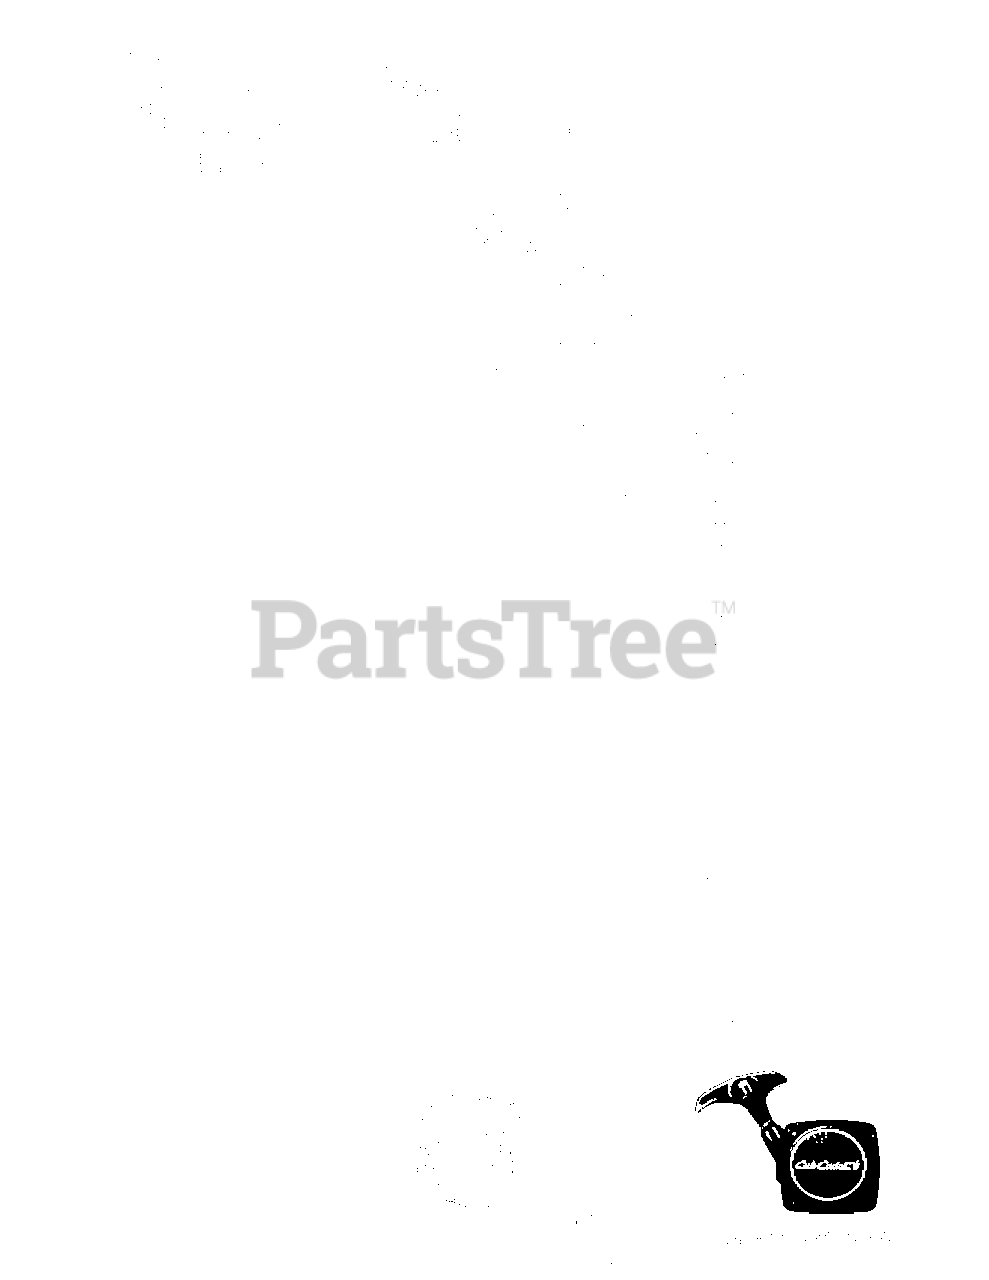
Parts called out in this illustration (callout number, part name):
1	Throttle Grip Assembly (includes 2-7)
3	Anti-R otation Screw
4	Throttle Cable Mounting Screw
5	Throttle Trigger
6	Throttle Trigger Spring
8	Throttle Cable
9	Harness Clip
12	D-Handle Base
13	Upper Drive Shaft Assembly
14	Split Boom Coupler Assembly (includes 15-18)
17	Knob (includes 18)
18	Nut
19	Lower Drive Shaft Housing Assembly
20	Lower Flex Shaft
21	Gearbox Mounting Hardware
22	Shield Mounting Hardware
23	Gearbox Assembly (includes 13, 21, 36 & 37)
24	Shield Assembly (includes 25)
25	Blade Assembly
26	Spool Shaft
27	Outer Spool Assembly (includes 28)
28	Retainer
31	Bump Head Knob Assembly
32	Engine Assembly
33	Anti-Rotation Screw
34	Clamping Screw
35	Nut
36	Gearbox Spacer
